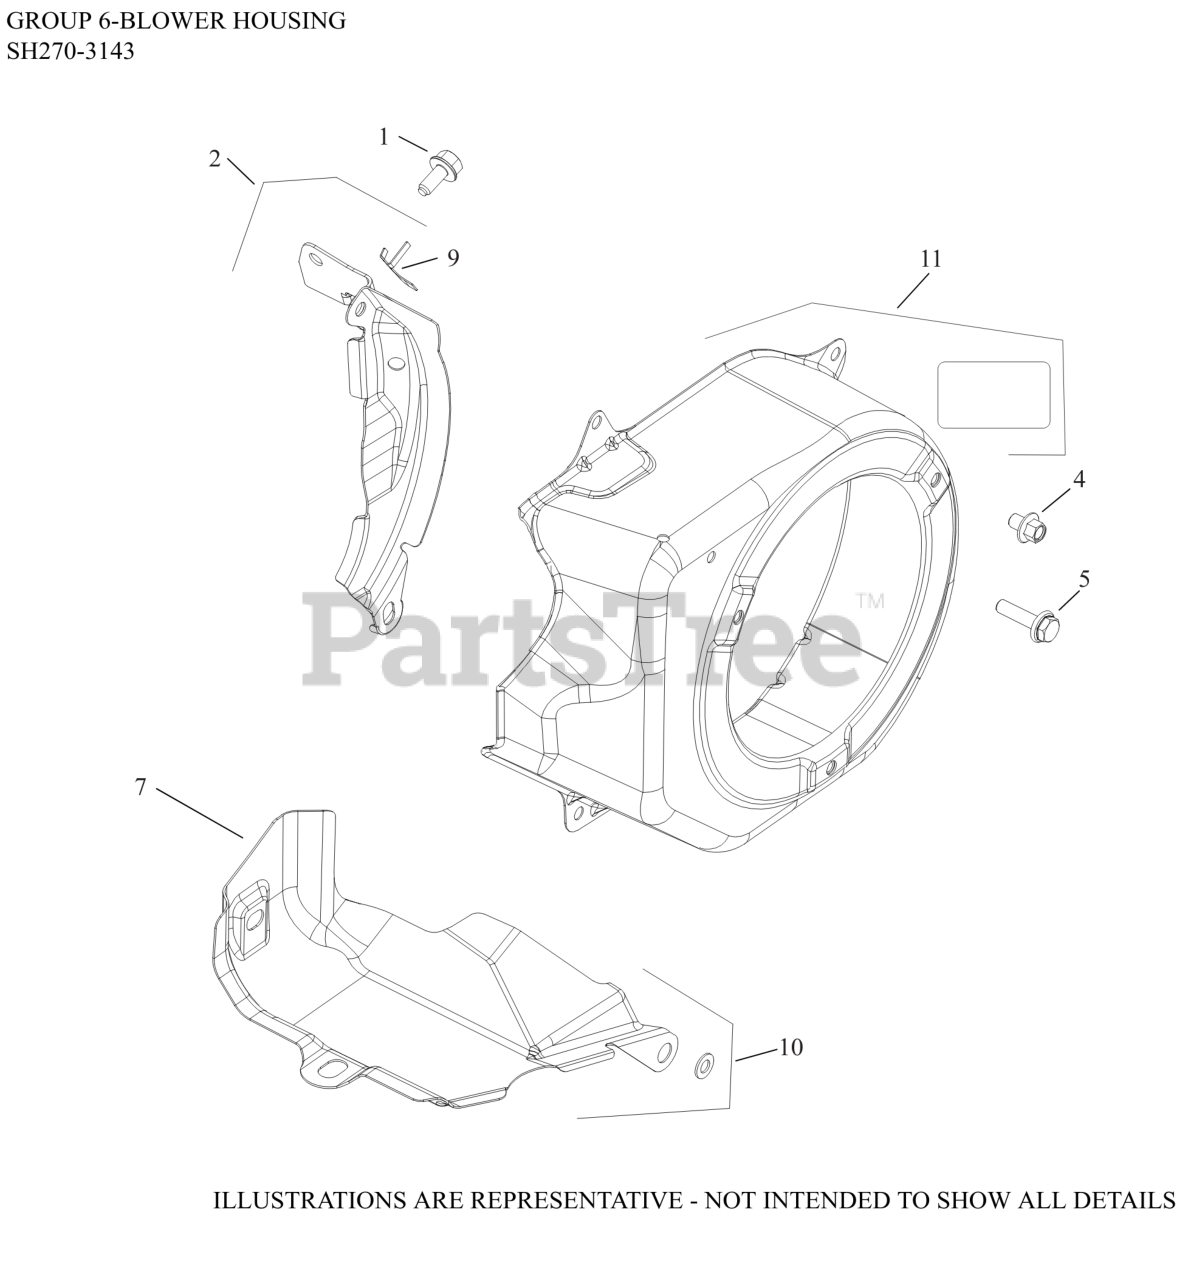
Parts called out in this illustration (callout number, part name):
1	SCREW, HEX FLANGE (M6)-USE 25 086 433-S
1	SCREW, HEX FLANGE (M6)
2	COVER, HOUSING LOWER BLOWER ASSEM
4	SCREW, M6 X 8 HEX FLANGE HEAD
5	SCREW, M6 X 22
9	CLIP, WIRE HARNESS-DISCONTINUED
10	KIT, CYLINDER SHIELD
11	KIT, BLOWER HOUSING
